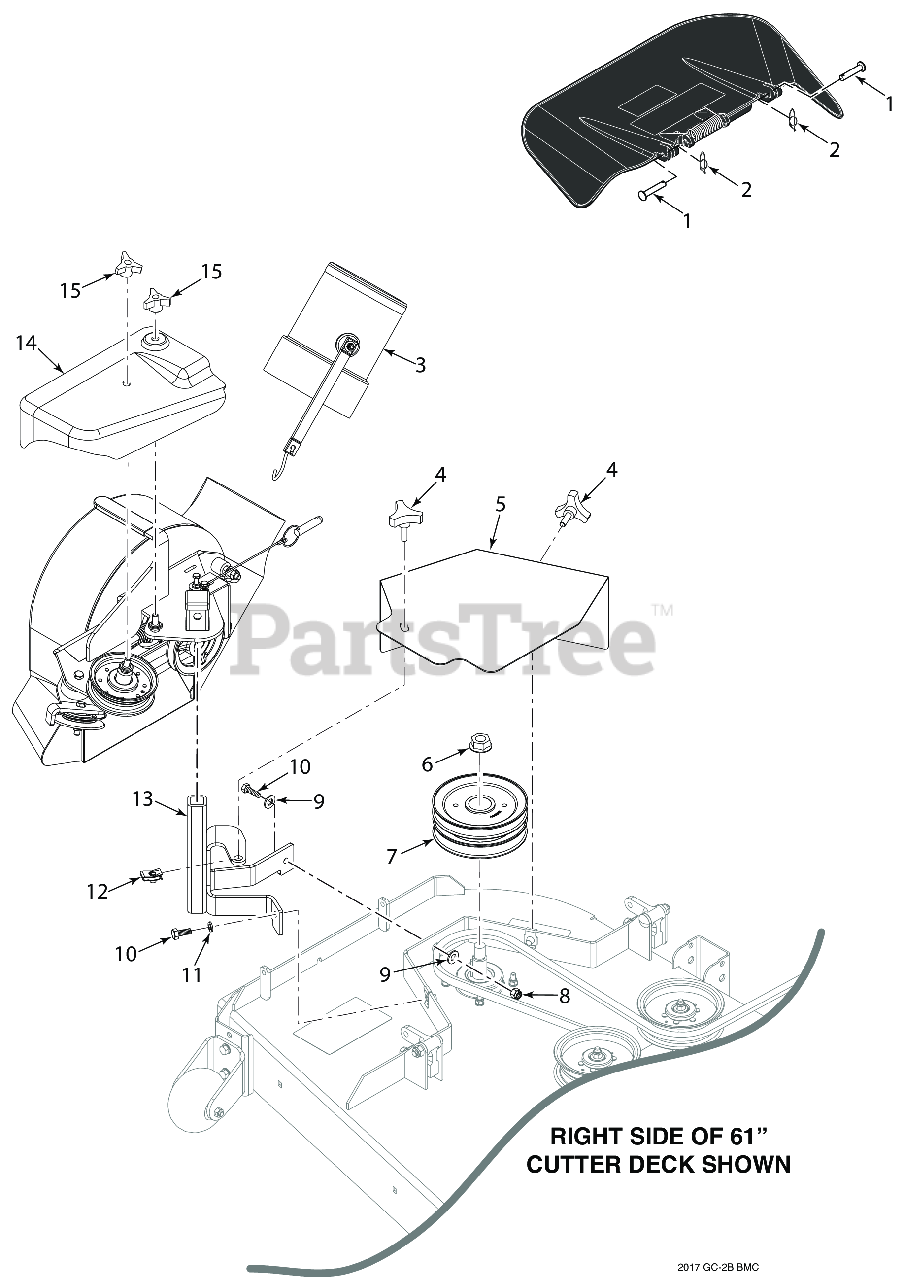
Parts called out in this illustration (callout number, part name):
1	Clevis Pin, 5/16 x 1-1/2"
2	Pin, Rue Cotter 5/16 Dia.
3	Adapter, Blower GC-STC,
4	Knob, w/stud 3/8-16 x 1-1/4"
5	Belt Cover - 52
5	Belt Cover - 61
6	Nut, 3/4-16 Spriral Lock
7	Pulley, Double Groove - 52
7	Pulley, Double Groove - 61
8	HEX NUT, ELASTIC STOP LOCK, 3/8-16
9	Flatwasher, 3/8" Special (.391 x .938 x .105)
10	Bolt, Hex Head 3/8-16 x 1-1/4", Kawasaki FX / FS
11	Lockwasher, 3/8" Spring, Kawasaki FX / FS
12	U-Nut, 3/8-16 (short)
13	Mounting Post Assembly, Blower - 52
13	Mounting Post Assembly, Blower - 61
14	Belt Cover - 52
14	Belt Cover - 61
15	Wing Nut, 3/8-16 (Small) Top side
